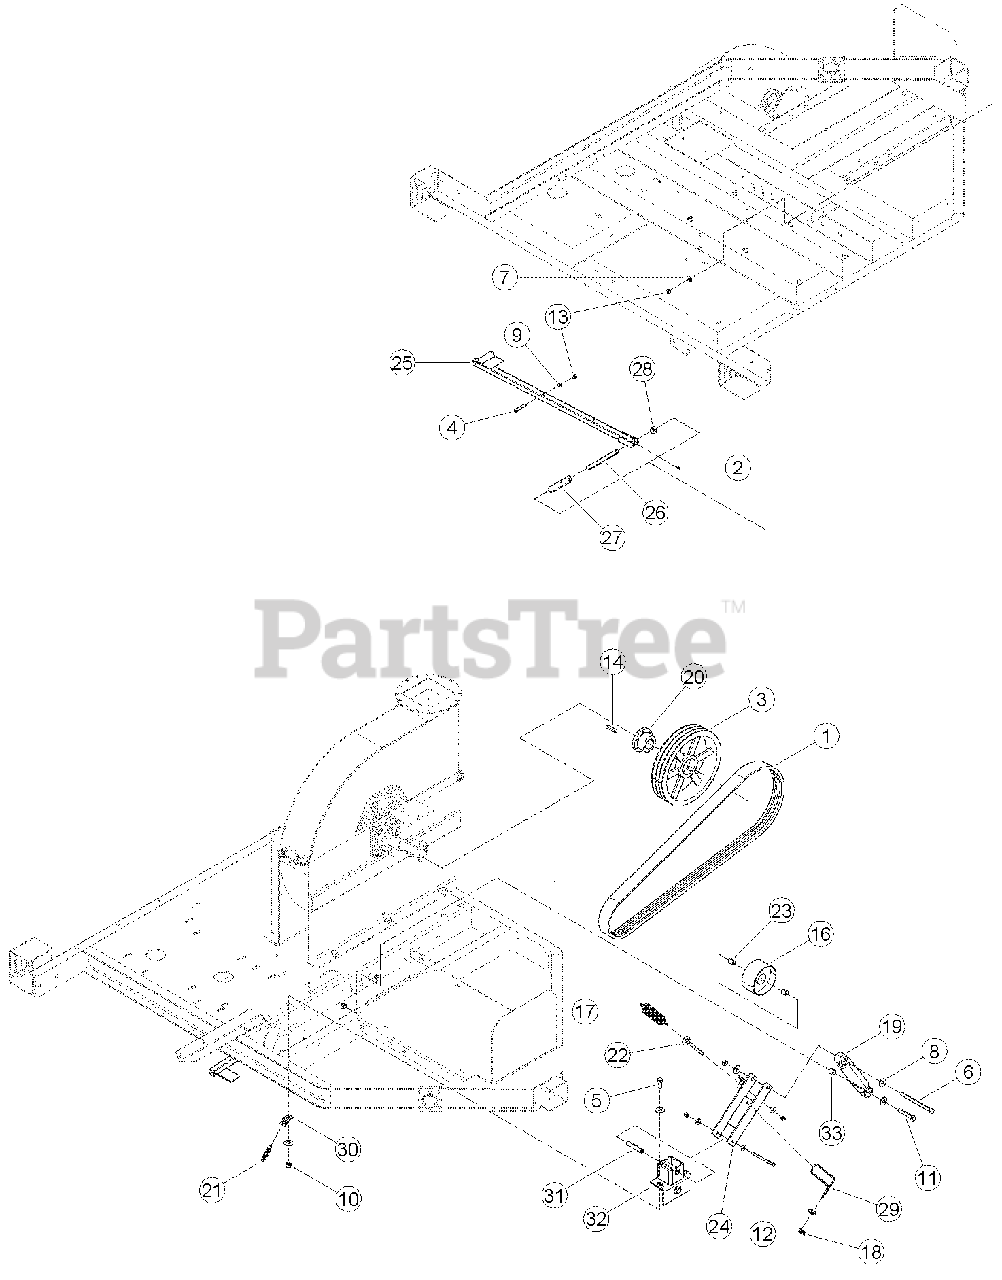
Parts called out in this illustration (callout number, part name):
1	BELT, 3B90 BANDED (CH922DH)
1	BELT, 3B83 BANDED (CH911DH)
2	FITTING, 1/4 SELF-TAP GREASE
3	SHEAVE, 3BQ12.4 SK (CH922DH)
3	SHEAVE, 3BQ11.0, SK (CH911DH)
4	BOLT, 3/8 X 2 HEX HD GR5 ZP
5	BOLT, 1/2 X 1-1/4 HHCS NC ZP
6	BOLT, 1/2 X 6-1/2 HCS GR5 ZP (CH922DH)
6	BOLT, 1/2 X 6 HEX HD GR5 ZP (CH911DH)
7	WASHER, 3/8 FLAT ZP
8	WASHER, 1/2 FLAT ZP
9	NUT, 3/8 HEX NC ZP
10	NUT, 1/2 CENTERLOCK GRB ZP
11	BOLT, 1/2 X 3 HEX HD GR5 ZP (CH922DH
11	BOLT, 1/2 X 3 1/4 HEX HD GR5 ZP (CH911DH)
12	BOLT, 3/8 X 4-1/2 HHCS GR5 NC ZP
13	NUT, 3/8 NE NYLOCK ZP
14	KEY, 3/8 SQUARE X 2 LONG PLAIN
15	BOLT, 3/8 X 7-1/2 HHCS GR5 NC ZP
16	PULLEY, IDLER 5 X 2.50
17	SPRING, 7-3/4 EXTENSION
18	CLAMP, 3/16 CABLE
19	ABSORBER, IDLER SHOCK
20	BUSHING, SK 1-3/4
21	SPRING, LT. EXT. .555 OD. X 2.75 LONG
22	EYEBOLT, 3/8 X 5, 4-1/4 THD ZP
23	SPACER, .75 X .90
24	WELDMENT, IDLER ARM
25	WELDMENT, CHIPPER CLUTCH PEDAL
26	SPACER, .63 X 6.44
27	SPACER, 1.0 X 4.25
28	SPACER, 1.0 X .50
29	CABLE, 3/16 X 24-1/2
30	ANGLE, SPRING ANCHOR
31	SPACER, .63 X 3.06
32	WELDMENT, IDLER SUPPORT (CH922DH)
32	WELDMENT, IDLER SUPPORT (CH911DH)
33	SPACER, 7/8 X 3/4
